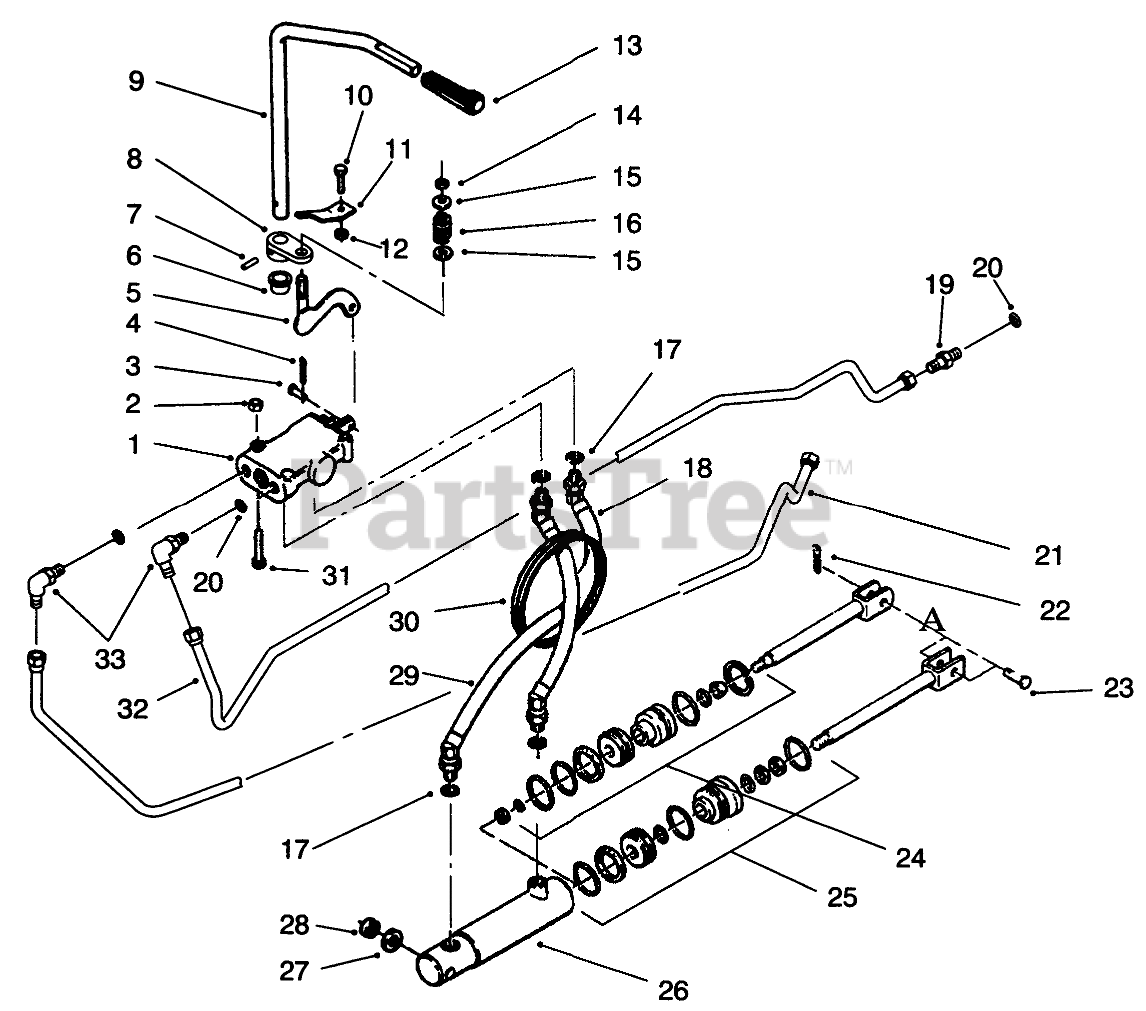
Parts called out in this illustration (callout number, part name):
1	Valve-Hydraulic (Incl. Ref. #3-4)
2	NUT-LOCK, NI
3	PIN-CLEVIS
4	PIN-COTTER
5	WLDMT-LIFT BAR
6	NYLINER BUSHING
7	SPIROL PIN 7/32X7/8
8	ARM-CONTROL
9	ROD-LIFT CONTROL
10	SCREW-HH
11	BRACKET-CONTROL R B
12	NUT-LOCK, NI
13	KNOB-HYDRAULIC LIFT
14	NUT-LOCK, NI
15	WASHER-PLAIN
16	SPRING
17	O RING
18	Hose ASM-Hydraulic
19	Fitting-Straight Adapter (Incl. Ref. #20)
20	0-Ring
21	TUBE-HYD PRESSURE
22	PIN-COTTER
23	Pin-Clevis
24	S/A O-RING&GASKET AS
25	S/A 108872 HYD CYL
26	Cylinder-Hydraulic (Incl. Ref. #24-25)
27	Washer
28	SPACER-OUTER
29	Hose ASM-Hydraulic
30	GROMMET
31	SCREW-HH
32	TUBE-HYDRAULIC
33	Fitting-90 (Incl. Ref. #20)
